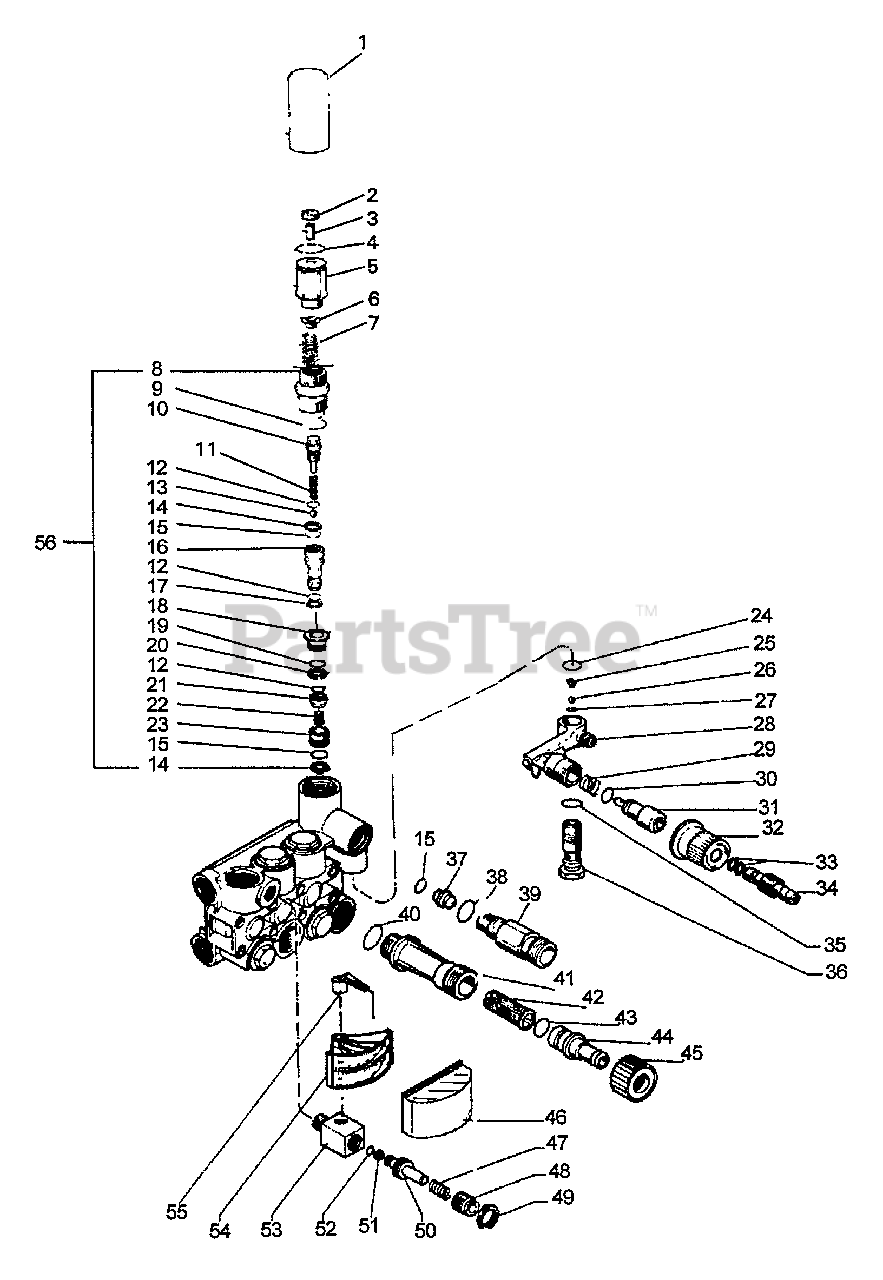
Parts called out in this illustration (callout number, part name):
1	KNOB, PRESSURE REGULATOR
2	NUT - 8
3	SCREW M8×16
4	O-RING 20 35×1 78
5	SCREW, PRESSURE SET
6	PLATE, SPRING
7	SPRING
8	BUSHING, GUIDE
9	O-RING 0.797×.103
10	STOPPER, STROKE
11	SPRING
12	O-RING
13	BALL - 9/32"
14	RING, ANTI-EXTRUSION
15	O-RING 9 92×2 62
16	PISTON, CONTROL
17	RING, ANTI-EXTRUSION
18	GUIDE, VALVE
19	O-RING
20	RING, ANTI-EXTRUSION
21	VALVE, BALL
22	SCREW M5×8×75
23	SEAT, VALVE
24	O-RING
25	SPRING, TAPER
26	BALL
27	O-RING 5 28×1 78 VITON
28	INJECTOR BODY
29	SPRING
30	O-RING
31	SHUTTER, INJECTOR
32	KNOB, CHEMICAL REGULATOR
33	O-RING
34	FITTING, HOSE BARB
35	O-RING
36	SEAT, CHEMICAL VALVE
37	NOZZLE
38	O-RING, VITON
39	FITTING, GREASE
41	FITTING, GREASE
44	FITTING, HOSE BARB
45	NUT, RING
46	COVER
47	SPRING
48	SCREW M14×1
49	NUT M14×1×17×3
50	PISTON
51	RING
52	O-RING 3 63×1 78 VITON
53	BODY
54	DIAL
55	INDICATOR
56	VALVE KIT
